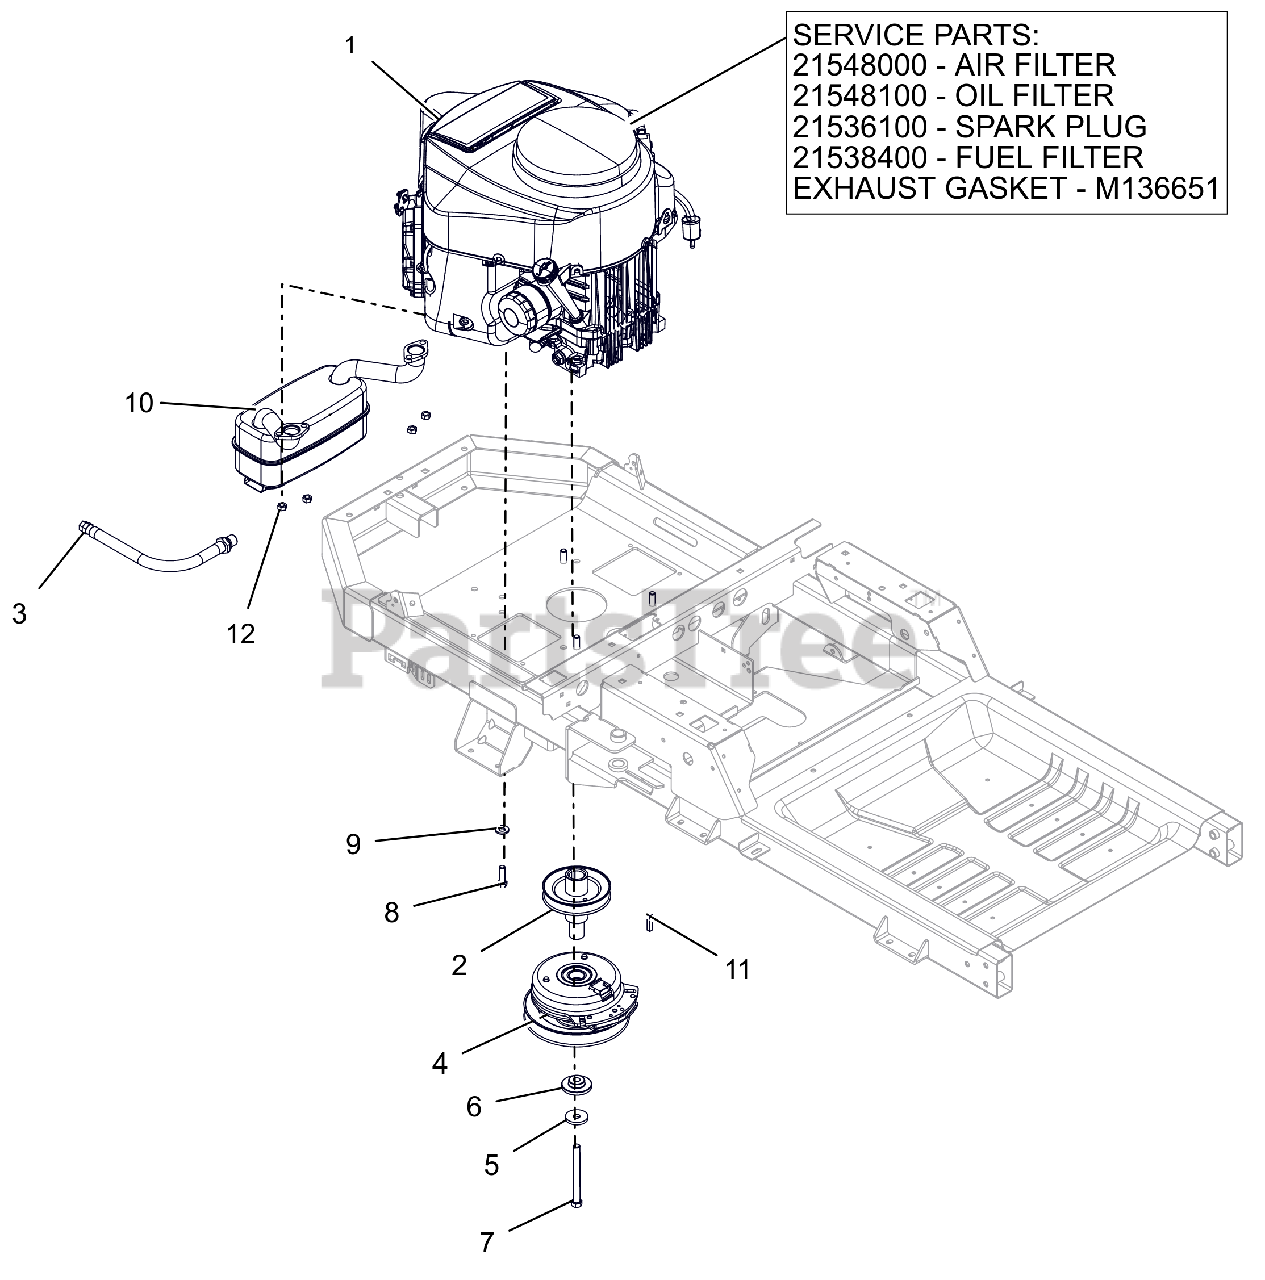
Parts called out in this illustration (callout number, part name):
1	ENGINE, KAWASAKI FR651V 22HP
1	AIR FILTER, KAWASAKI FR
1	OIL FILTER, KAWASAKI FR
1	PLUG, SPARK
1	FUEL FILTER - KAWASAKI
1	GASKET, MUFFLER #
2	WLDMT, DRIVE SHEAVE-X
3	HOSE, OIL DRAIN
4	CLUTCH,105FTLB MONOPOLE 6.83"
5	WASHER, 7/16" SPRING DISK
6	BSHG-FLG .469X1.06X.574X2.0
7	BLT-HEX.438-20X4.5GR8YZ NYTORQ
8	BLT-HEX.38-16X1.25 G5YZ NYTORQ
9	WASHER, 3/8" SPRING DISC
10	MUFFLER - KAWASAKI
11	KEY-SQ .25 X 1.25 X .25 SAE
12	NUT-LK-TOP M8-1.25 YWZC
